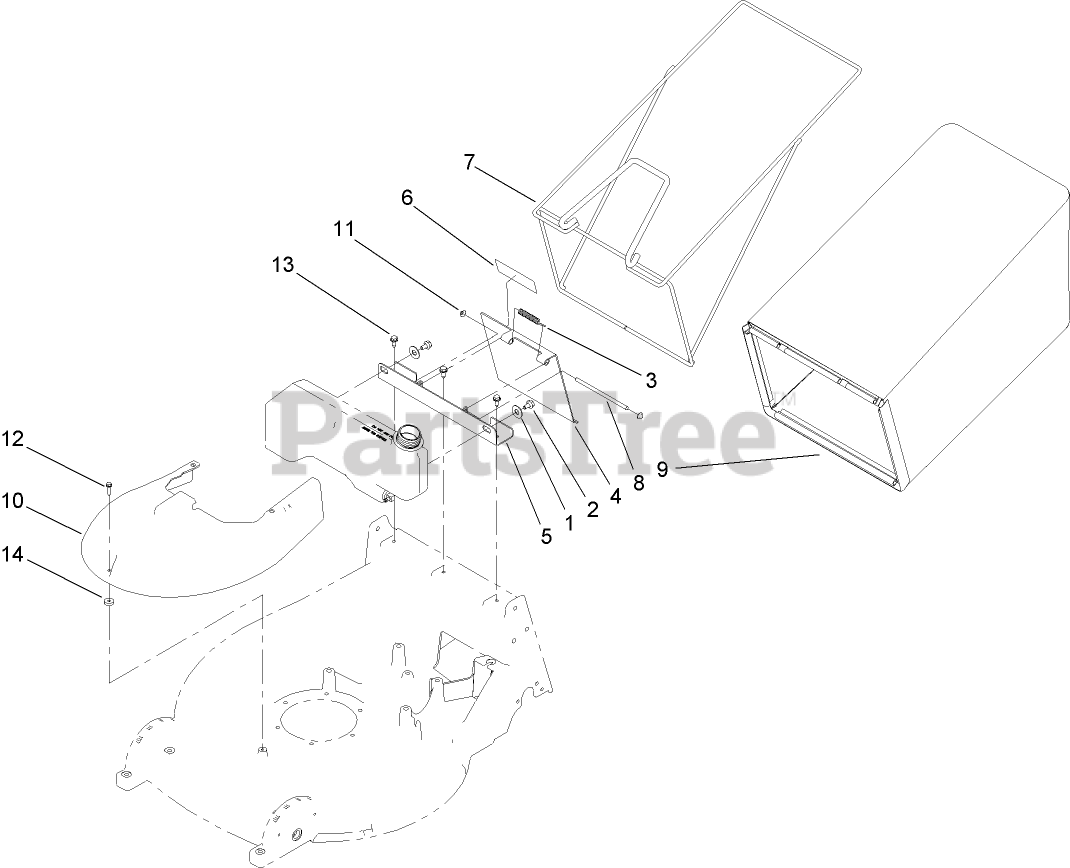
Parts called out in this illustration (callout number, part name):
1	WASHER-PLASTIC
2	BOLT-SHOULDER
3	SPRING-TORSION
5	BRACKET-MOUNT, BAG/DOOR
6	DECAL-DANGER
7	FRAME-BAG
8	ROD-PIVOT, DOOR
9	GRASS BAG ASM
10	COVER-SPINDLE
11	NUT-PUSH
12	SCREW-HWHTF
13	SCREW-HWHTF
14	WASHER
